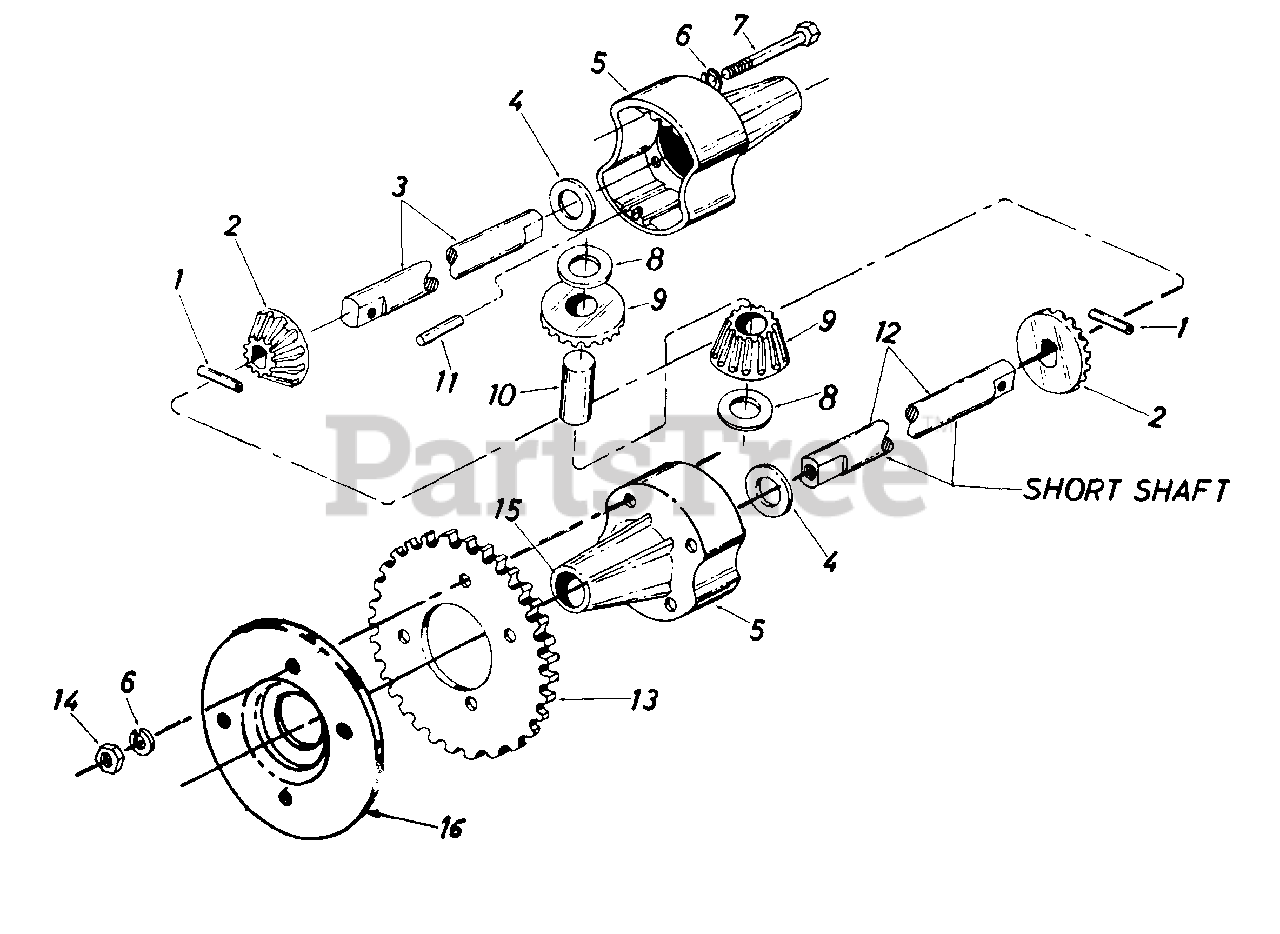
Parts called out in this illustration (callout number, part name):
1	Spring Pin Spiral 3/16" Dia. x 1.00" Lg.
2	Gear - Double "D" Hole
3	Shaft - Long - 19.81" Lg.
4	Fl-Wash. .760 I.D. x 1.49 O.D.
5	Housing Half
6	L-Wash. 5/16" I.D.
7	Hex Bolt 5/16-24 x 4.00" Lg.
8	Fl-Wash. .640 I.D. x .24 O.D.
9	Gear - Round Hole
10	Drive Pin
11	Dowel Pin 3/16" Dia. x .62" Lg.
12	Shaft - Short - 8.52" Lg.
13	Sprocket - 48 Teeth
14	Hex Cent. L-Nut 5/16-24 Thd.
15	Flange Bearing
16	Brake Disc
